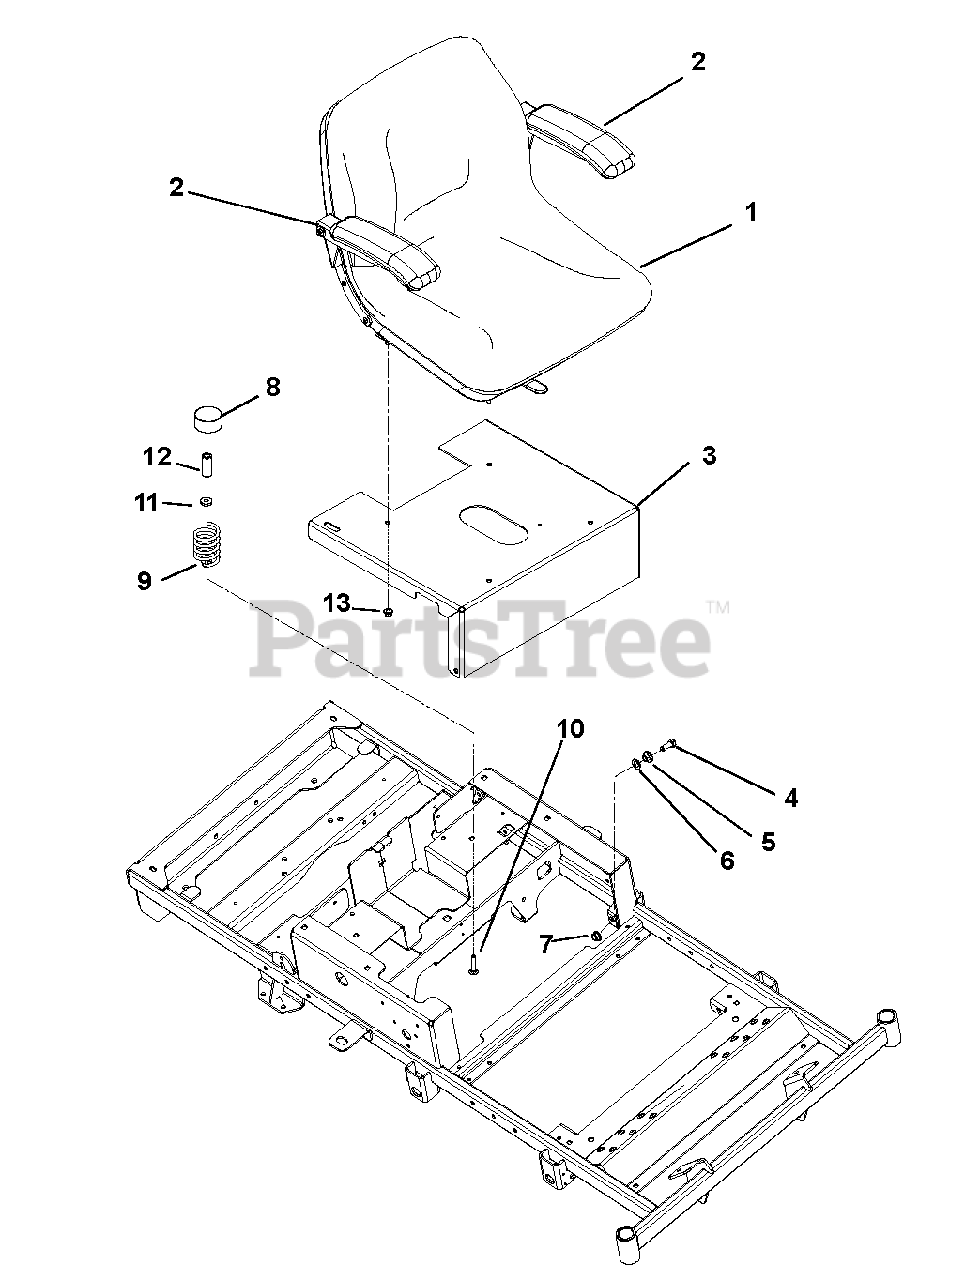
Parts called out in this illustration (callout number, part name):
1	Seat with Arm
2	Arm Rest Kit
3	Seat Plate
4	Bolt, Hex .38-16 x 1.00 Grade 5
5	Bushing, Flange .385 x .500 x .875 x .406
6	Washer, Flat Steel .52 x .827 x .062
7	Nut, .38-16 Nyloc Flange
9	Spring, Seat
10	Bolt, Round Head Square Neck .31-18 x 1.50 Grade 5
11	Washer, Flat Steel .328 x .87 x .179
12	Nut, Coupling 5/16-18 x 1 .75
13	Nut, 5/16-18 Flange Nyloc
